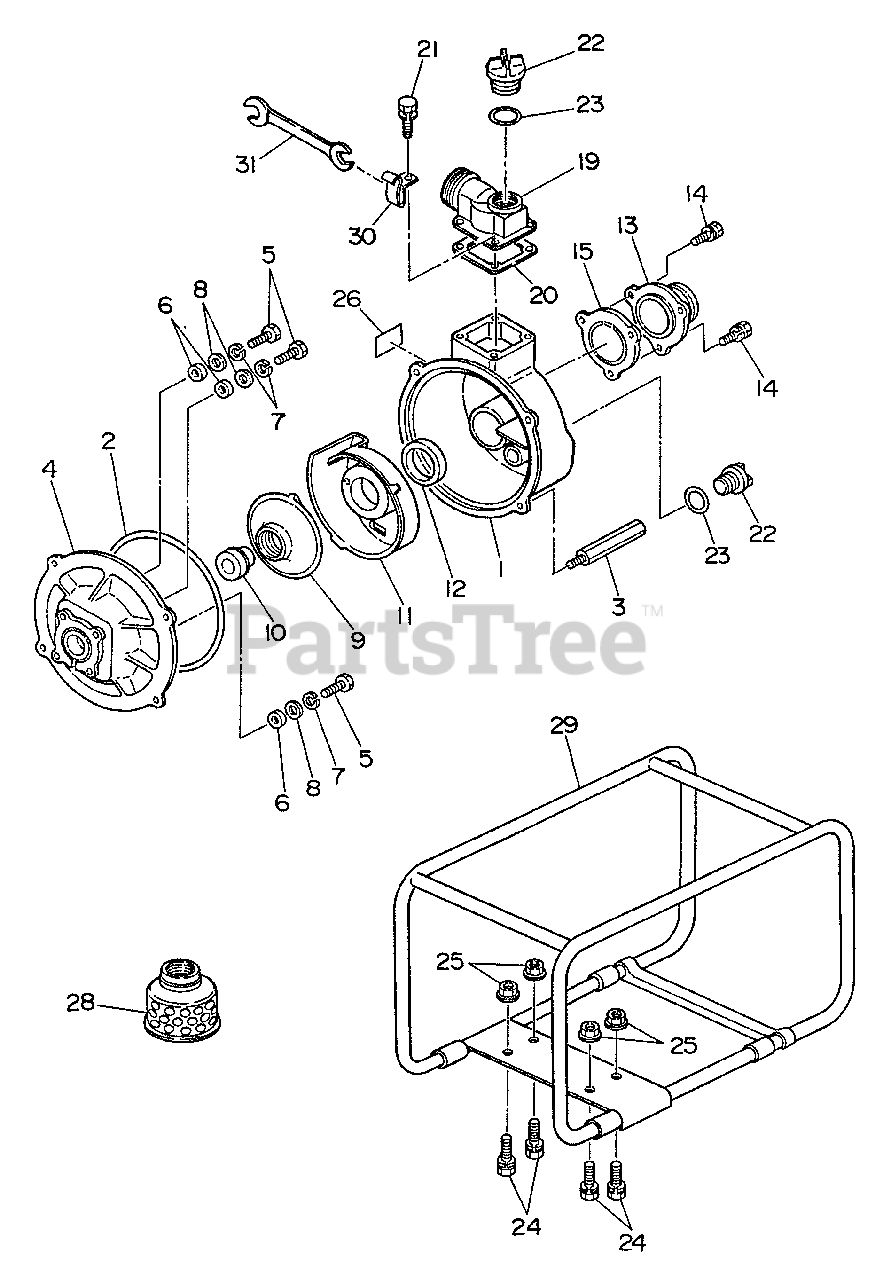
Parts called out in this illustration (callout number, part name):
2	GASKET
3	BOLT
4	COVER, PUMP CASE
7	LOCKWASHER
11	INNER CASING
13	SUCTION FLANGE (NPT)
14	BOLT
15	VALVE, CHECK
19	DELIVERY FLANGE (NPT)
20	PACKING
21	BOLT
22	PLUG
24	BOLT
25	NUT - FLANGE
26	LABEL - PUMP
28	STRAINER, DEBRIS
30	HOOK
